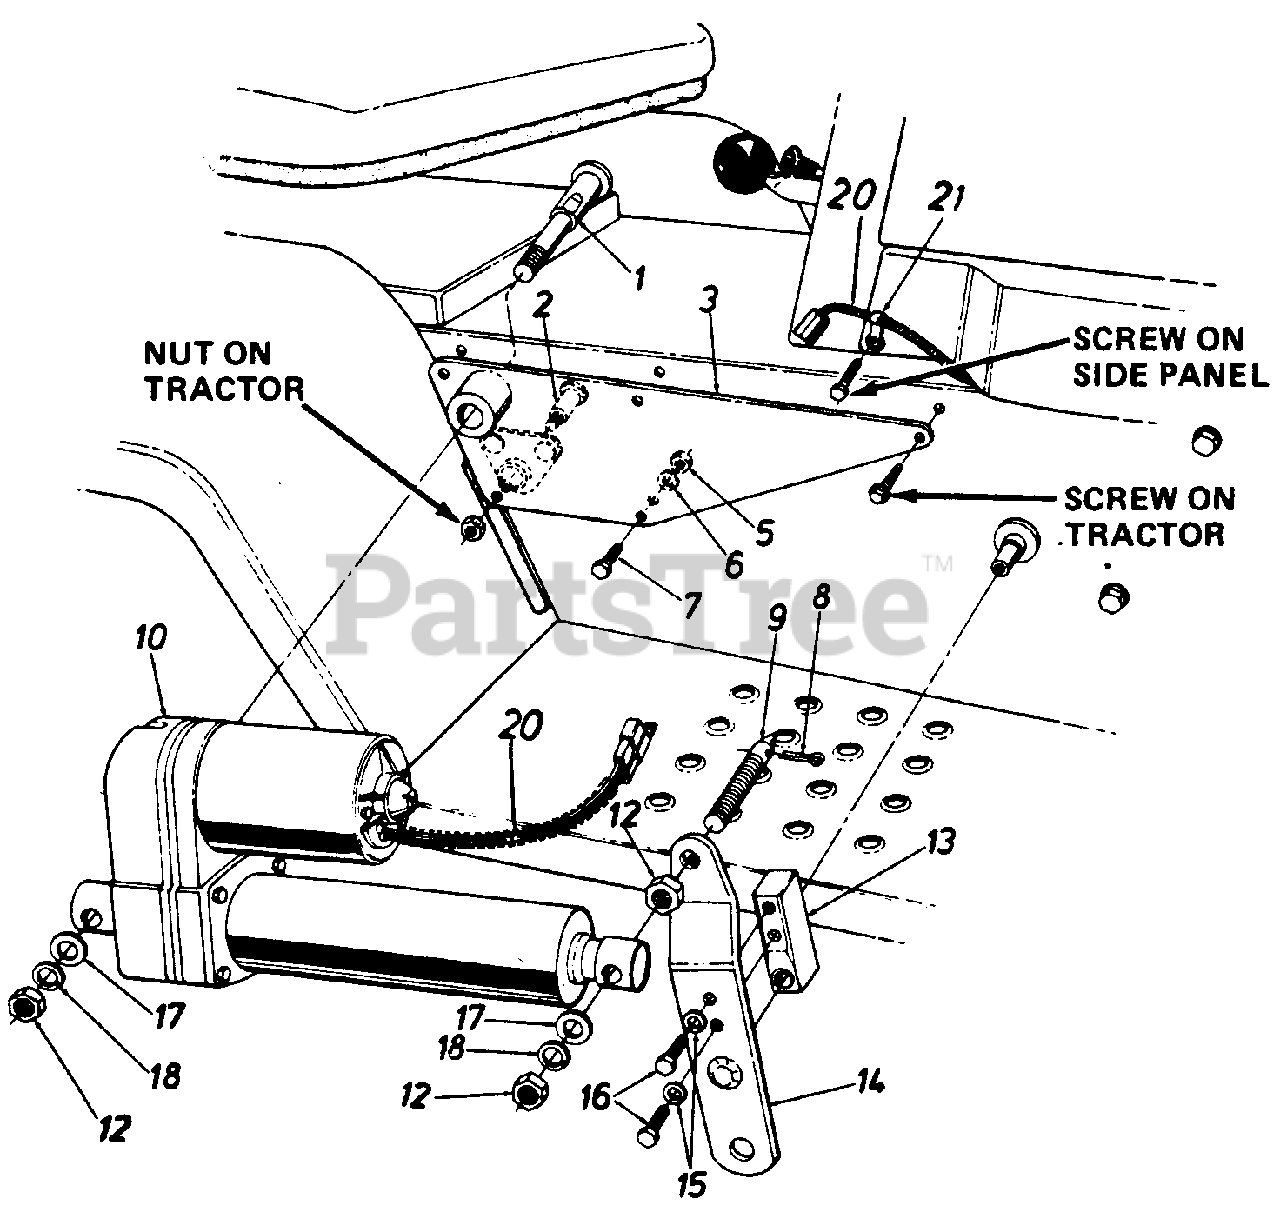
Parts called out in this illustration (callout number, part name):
1	Pivot Pin
2	Shld. Bolt.626 Dia. x .96"
5	Hex Nut 1/428 Thd.
6	L-Wash. 1/4" I.D.
7	Hex Bolt 1/4-28 x .75" Lg. (Grade 5)
8	Cotter Pin
9	Indicator & Mtg. Pin
10	Electric Actuator
10	Toggle Switch
12	Hex Jam Nut 1/2-13 Thd.
13	Lift Shaft Drive
14	Lift Bracket Ass'y.
15	L-Wash. 5/16" I.D.
16	Hex Bolt 5/16-24 x 1.0" Lg. (Grade 5)
17	Fl-Wash. .53" I.D. x.93" O.C.
18	L-Wash. 1/2" I.D.
18	Wire Harness
20	Plastic Tubing-7"
21	Clamp
